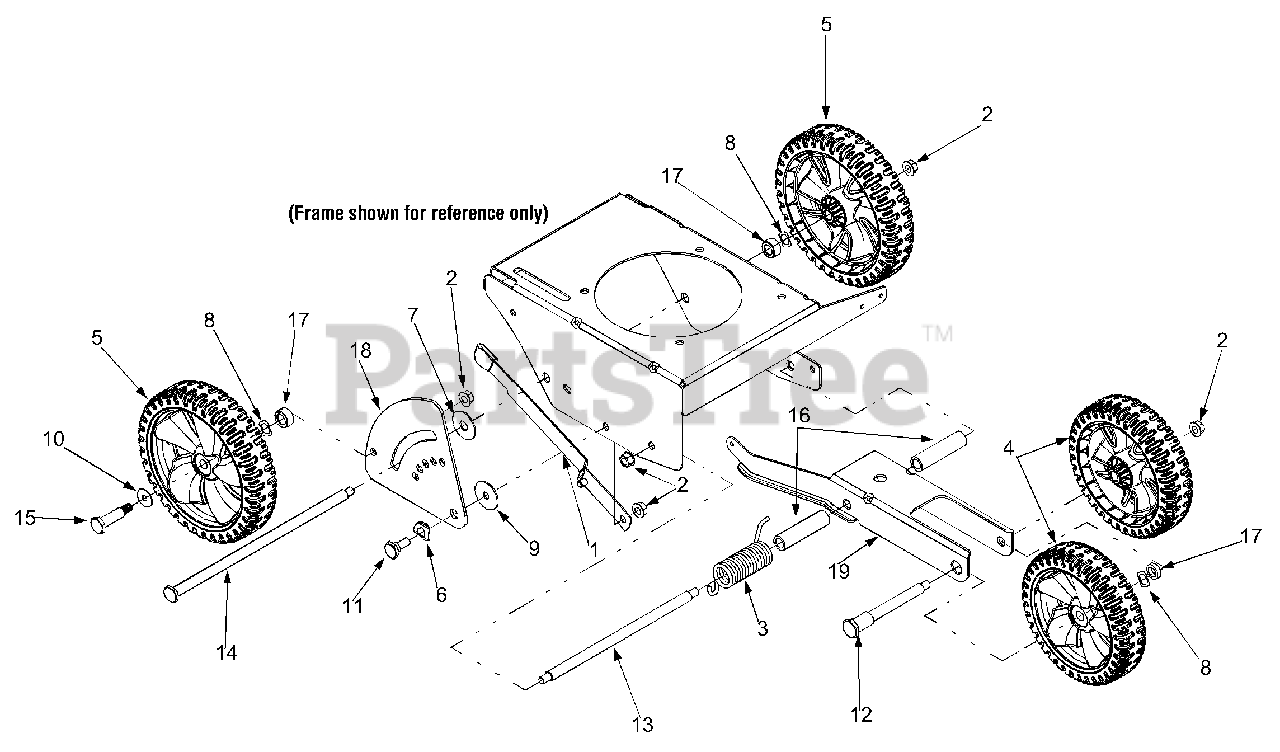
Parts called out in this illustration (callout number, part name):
1	Curb Height Adjustment Lever
2	Flange Lock Nut, 3/8-16
3	Torsion Spring
4	Wheel 7 x 1.75
5	Wheel 8 x 1.75
6	Spring Washer,.500 x 1.00
7	Flat Washer,.51 ID x 1.5 OD
8	Wave Washer,.531 ID x.781 OD
9	Washer,.385 x 1.5
10	Flat Washer,.510 x 1.00
11	Shoulder Screw,.50 x.27
12	Shoulder Screw,.50 x 4.62
13	Shoulder Screw,.50 x 9.36, 3/8-16
14	Shoulder Screw,.50 x 11.61
15	Shoulder Screw,.498 x 2.045
16	Spacer,.525 x.688
17	Spacer,.505 ID x.88 OD
